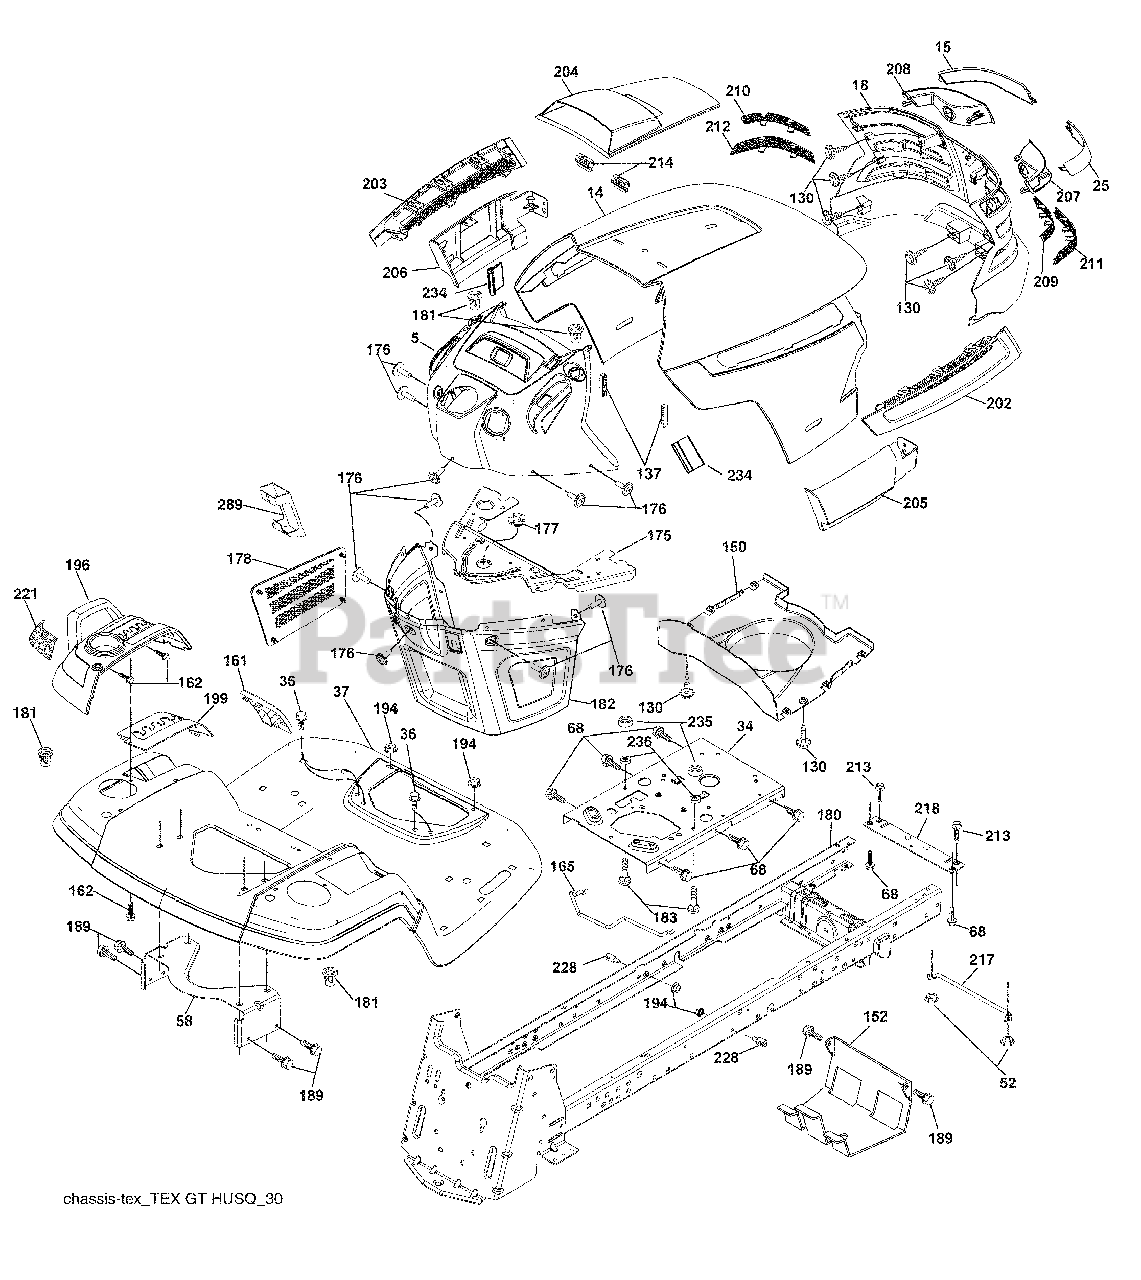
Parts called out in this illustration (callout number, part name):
14	Hood
18	Grille Asm.
34	Plate Engine
36	Screw 5/16-18 x 3/4
37	Fender
52	Nut Crown Lock 5/16-18
58	Bracket Fender
68	Screw 5/16-18 x 1/2
130	Screw #10 x .750 BOS Thread
137	Bumper Dash
150	Duct Heat Hood
152	Shield Browning/Debris
161	Console Fuel Window
162	Screw Hex Wsh Hi-Lo 1/4 x 1/2
165	Bracket Support Tank
175	Crossmember
176	Screw 10-24 x 5/8 Wshd Qdrx
177	Bushing Steering
178	Cargo Asm. Net
180	Chassis
181	Bushing Mtg. Fender Crgo.
182	Dash Lower
183	Bolt Fin Hex 5/16-18 unc x 1-1/4
189	Screw 5/16-18 x 3/4
194	Nut Lock Hex Flange 5/16-18
196	Console Asm. Deck Lift
199	Plate Deck Lift
202	Vent Side Hood RH
203	Vent Side Hood LH
204	Vent Asm Hood Top
205	Skirt Hood Side RH
206	Skirt Hood Side LH
209	Insert Hex Top RH
210	Insert Hex Top LH
211	Insert Hex Bottom RH
212	Insert Hex Bottom LH
213	Bolt Hex Hd 5/16-18 unc x 3/4
214	Clip Retainer
221	Reflector LH
228	Stud Fastener
234	Bumper Hood
235	Spacer Fender
236	Nut Center Lock 5/16-18 unc
289	Plug Cruise Control/Phone
